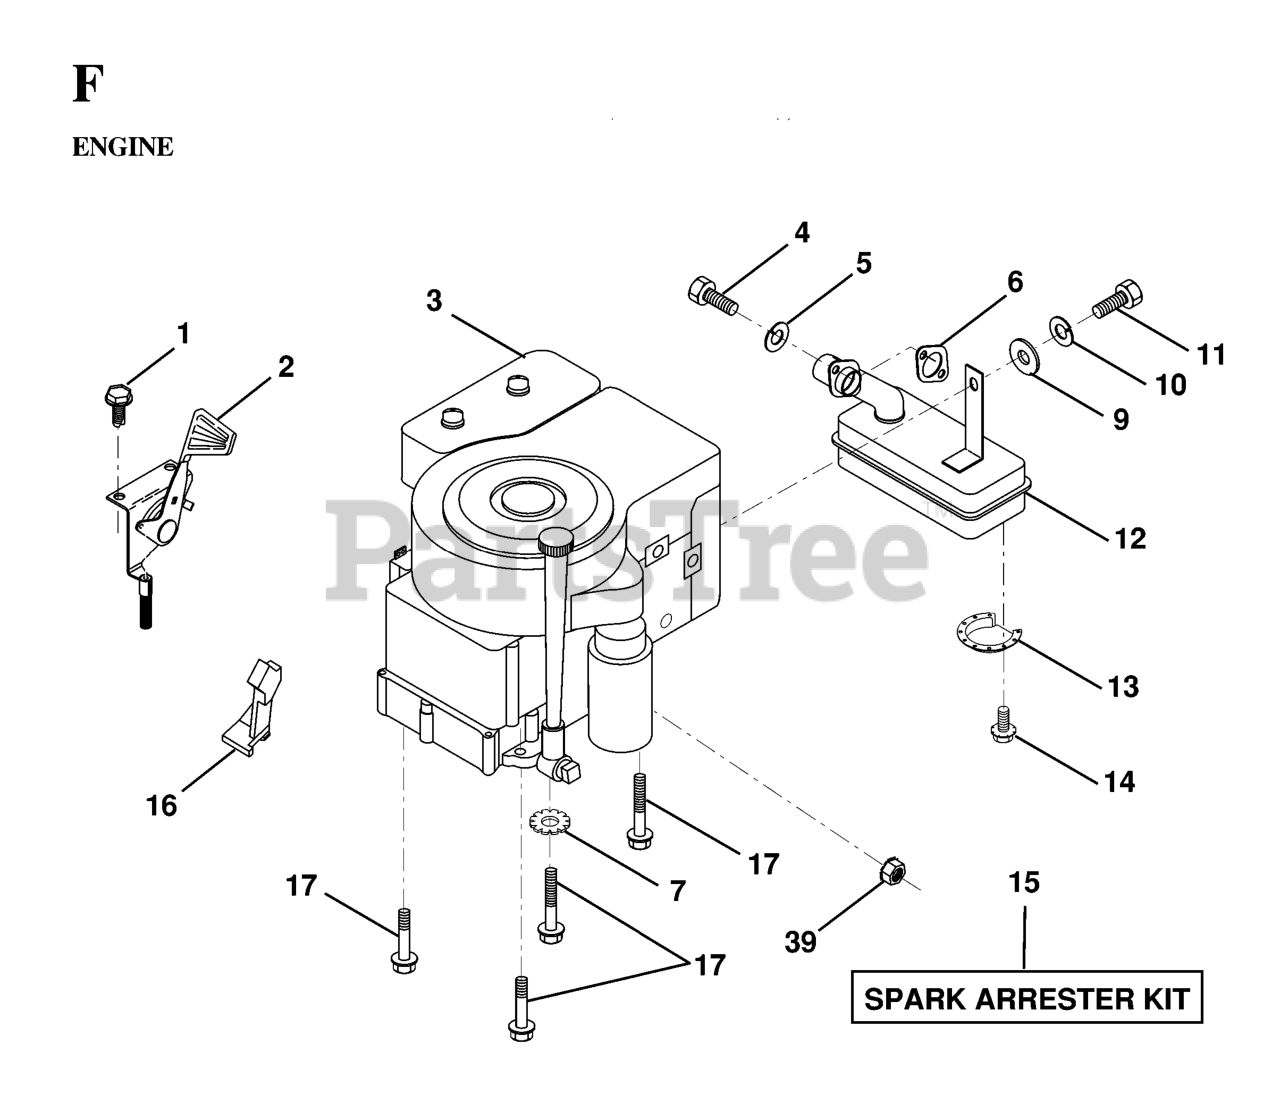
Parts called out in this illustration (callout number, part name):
2	CONTROL.TH/CH.RH.BLK.FLG.EEC
4	SCREW
5	WASHER.LOCK.HVY.HLCL.SPR.5/16
6	GASKET.ENG.1.313 ID.TIN PLATED
7	LOCKWASHER
9	WASHER
10	LOCKWASHER
12	MUFFLER.SINGLE.B&S.12HP
13	DEFL MUFFLER LTV
14	SCREW
15	KIT.SPARK ARRESTOR 794945 B&S
16	STOP THROTTLE
17	SCREW LT
39	NUT FLANGE 1/4-20 STARTER NUT
